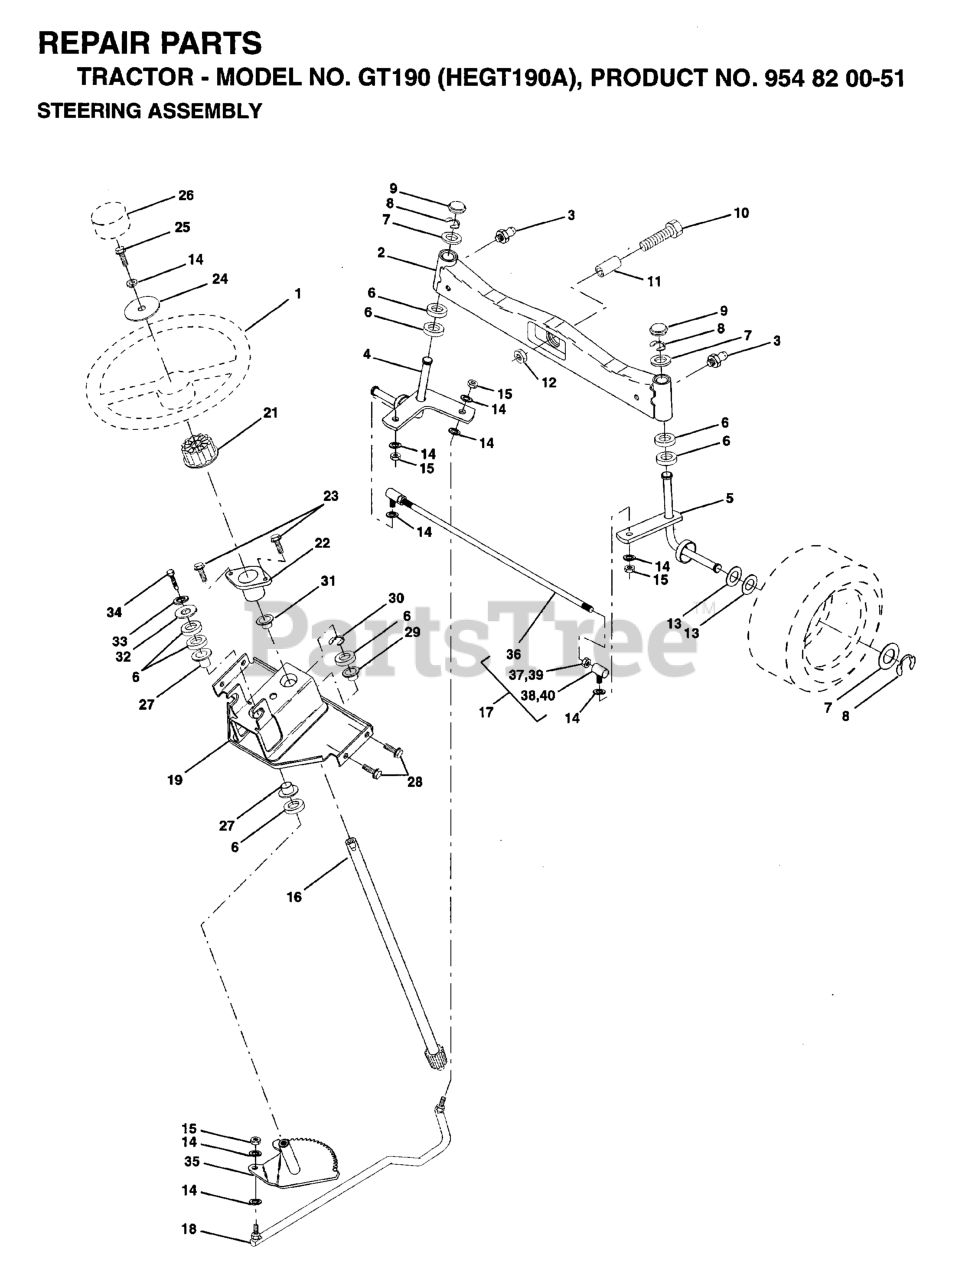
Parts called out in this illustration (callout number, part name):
1	STEERING WHEEL
2	FRONT AXLE ASSY
3	ZERK M
4	SPINDLE ASSY LH
5	SPINDLE ASSY RH
6	THRUST WASHER
9	CAP.SPINDLE.BLACK
10	Bolt, Hex 5/8 -11 x 2 - 3/4 Gr. 5
11	TUBE, PIVOT AXLE
12	NUT-LOC,FLANGE LT
14	WASHER, LOCK 3/8
15	NUT
16	SHAFT ASM, STEERING
17	ROD ASSY/TIE BALL
18	DRAGLINK-BALL JOINT SOLID
19	SUPPORT ARM, STEERING VGT
21	ADAPTER LT
22	BUSHING LT
23	SCREW LT
24	WASHER T
26	INSERT,STR WHEEL
27	BRNG T
28	SCREW
29	BEARING-FLANGE GT
30	Ring, Klip Truarc #5304-75
31	BUSHING.NYLINER.
33	WASHER.LOCK.HVY.HLCL.SPR.5/16
34	BOLT
35	GEAR.ASM.SECTOR.
36	TIE ROD
38	JOINT
